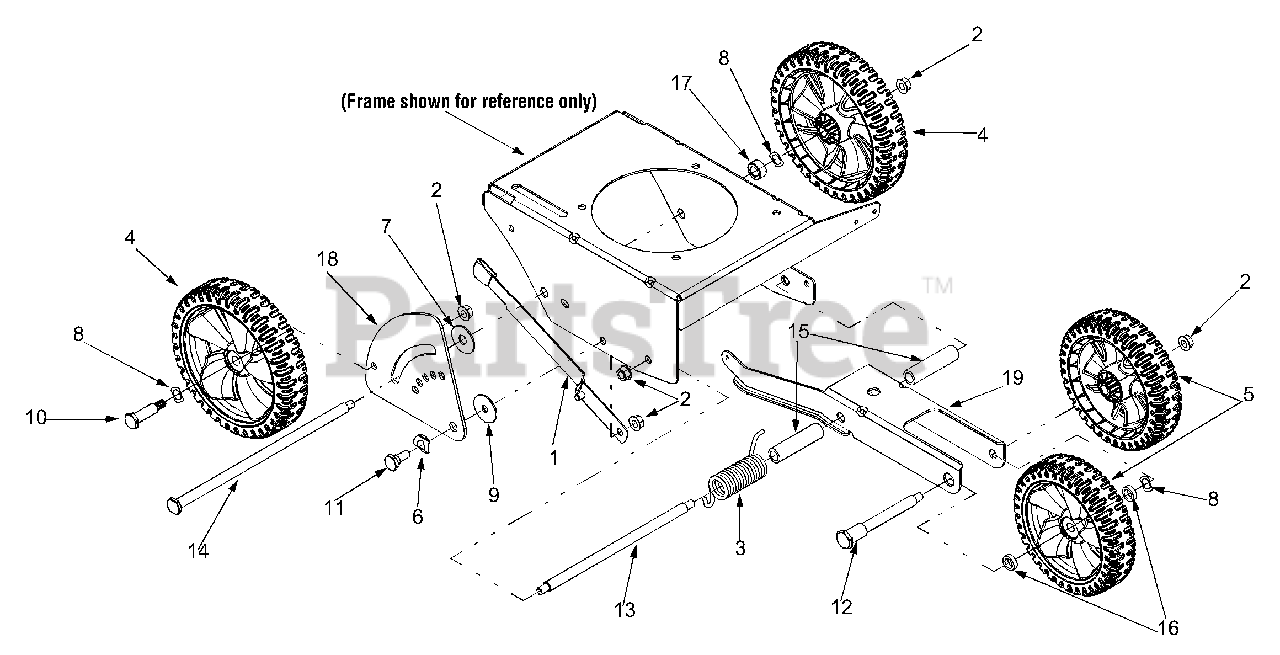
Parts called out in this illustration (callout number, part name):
1	Curb Height Adjustment Lever
2	Flange Lock Nut, 3/8-16
3	Torsion Spring
4	Wheel 8x1.8
5	Wheel 7x1.8
6	Spring Washer,.500 x 1.00
7	Flat Washer,.51 ID x 1.5 OD
8	Wave Washer,.531 ID x.781 OD
9	Washer,.385 x 1.5
10	Shoulder Screw,.498 x 1.445
11	Shoulder Screw,.50 x.27
12	Shoulder Screw,.50 x 4.62
13	Shoulder Screw,.50 x 9.36, 3/8-16
14	Shoulder Screw,.50 x 11.61
15	Spacer,.525 x.775
16	Spacer,.525 x.775
17	Spacer,.505 ID x.88 OD
